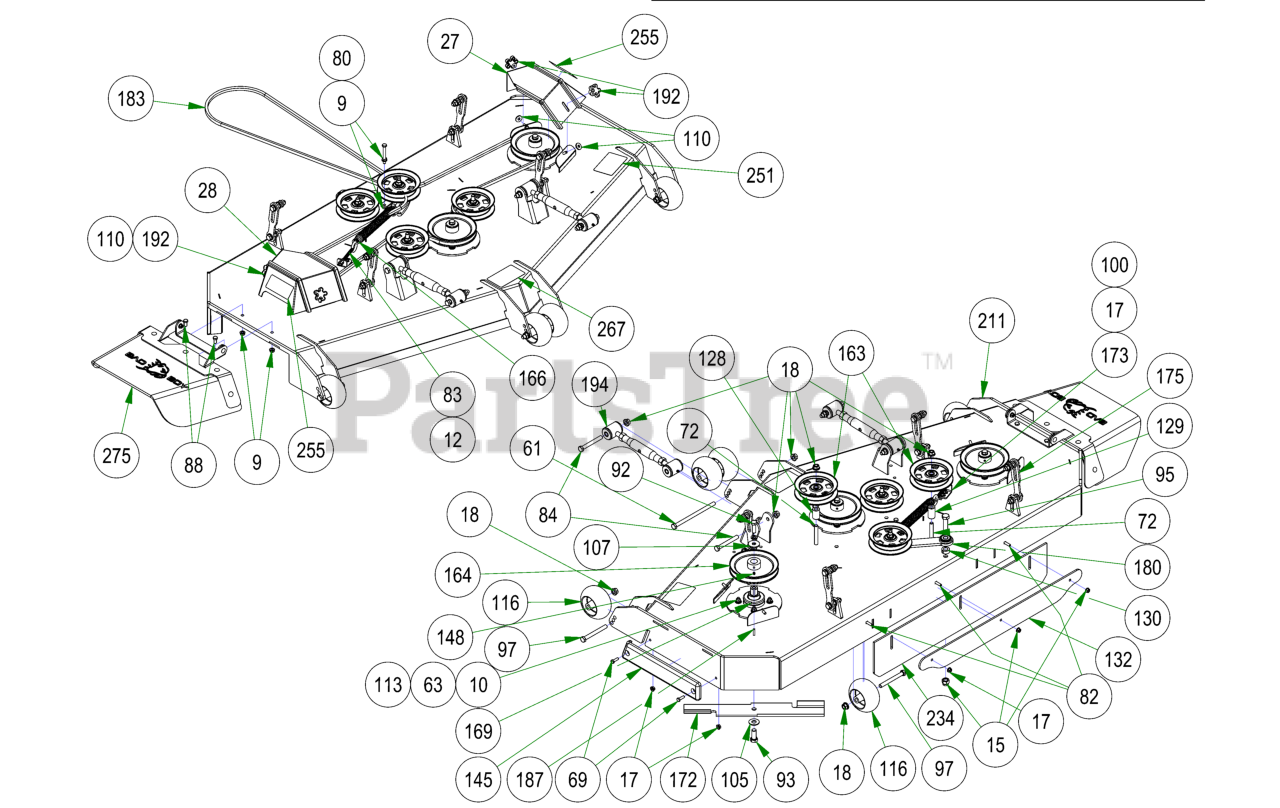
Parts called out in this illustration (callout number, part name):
9	3/8-16 HEX SERRATED FLANGE NUT HARD/ZINC
10	3/8-16 NYLON INSERT FLANGE LOCKNUT (GR.F) ZINC
12	3/8-16 HEX NUT ZINC
15	5/8-11 NYLON INSERT LOCKNUT ZINC
17	5/16-18 NYLON INSERT FLANGE LOCKNUT ZINC
18	1/2-13 NYLON INSERT FLANGE LOCKNUT ZINC
27	2019 72" Left Outlaw Gen2 Pulley Cover
28	2019 72" Right Outlaw Gen2 Pulley Cover
61	1/2-13 X 8 HEX CAP SCREW GR 5 ZINC
63	3/8-16 X 1-3/4 HEX C/S (GR.5) ZC
69	5/16-18 X 1 HEX CAP SCREW (GR.5) ZINC
72	1/2-13 X 3-1/2 HEX FLANGE BOLT (GR.8) ZINC
80	3/8-16 X 3 HEX CAP SCREW (GR.5) ZINC
82	5/16-18 X 1-1/4 CARRIAGE BOLT ZINC
83	4" 3/8-16 Eye Bolt
84	1/2-13 X 4 HEX CAP SCREW (GR.8) ZINC YELLOW
88	3/8-16 X 3/4 HEX CAP SCREW (GR.5) ZINC
92	1/2-20 X 1-1/2 HEX CAP SCREW (GR.5) ZINC
93	5/8-18 X 1-1/2 HEX CAP SCREW (GR.8) ZINC YELLOW
95	5/8-11 X 2-1/2 HEX CAP SCREW (GR.5) ZINC
97	1/2-13 X 4-1/2 HEX CAP SCREW (GR.5) ZINC
100	5/16-18 X 7/8 CARRIAGE BOLT ZINC
102	1/2 SPLIT LOCKWASHER (GR.8) ZINC/YELLOW
105	5/8 USS FLAT WASHER (1-3/4" OD) GR.8 ZINC YELLOW
107	1/2 BELLEVILLE WASHER (1-5/8 OD X .140 THK) ZINC
110	.360 ID X .983 OD X .120 THICK FLAT WASHER NYLON BLACK
113	5/16 USS FLAT WASHER (7/8 OD) ZINC
116	2019 Deck Wheel
128	.502 ID X .750 OD X 1.500 Long Spacer
129	1 3/4" Pulley Spacer
130	5/8 SOLID SHAFT COLLAR (W/1 SET SCREW) ZINC
132	61 Bolt in Baffle Deck v2 Stripping Plate
145	REVISED TRIM BUMPER_20180226
148	5/16-24 X 1/4 SOCKET SET SCREW (CUP PT) PLAIN
163	5-3/4 Idler Pulley
164	7" Deck Pulley
166	2019 Outlaw Gen2 Deck Spring
169	OUTLAW SPINDLE ASSEMBLY
172	72" High Lift Fusion Blade
173	2019 Deck Eye Bolt Tab
175	Deck Hanger Assembly
180	2019 Rebel Rogue Deck Idler
183	B202 Belt for 72" Outlaw
187	1/4 X 1 SQ MACHINERY KEY 1018 STL PLN
192	5/16" Knob
194	Turnbuckle
211	2019 Sloped 72" Deck
234	R Series Rubber For Deck
251	2018 72" Deck Decal
255	Danger Decal-Spindle/Discharge
267	2019 Rebel & Rogue Deck Belt Route Decal
275	2019 Outlaw Gen2 Chute Assembly
